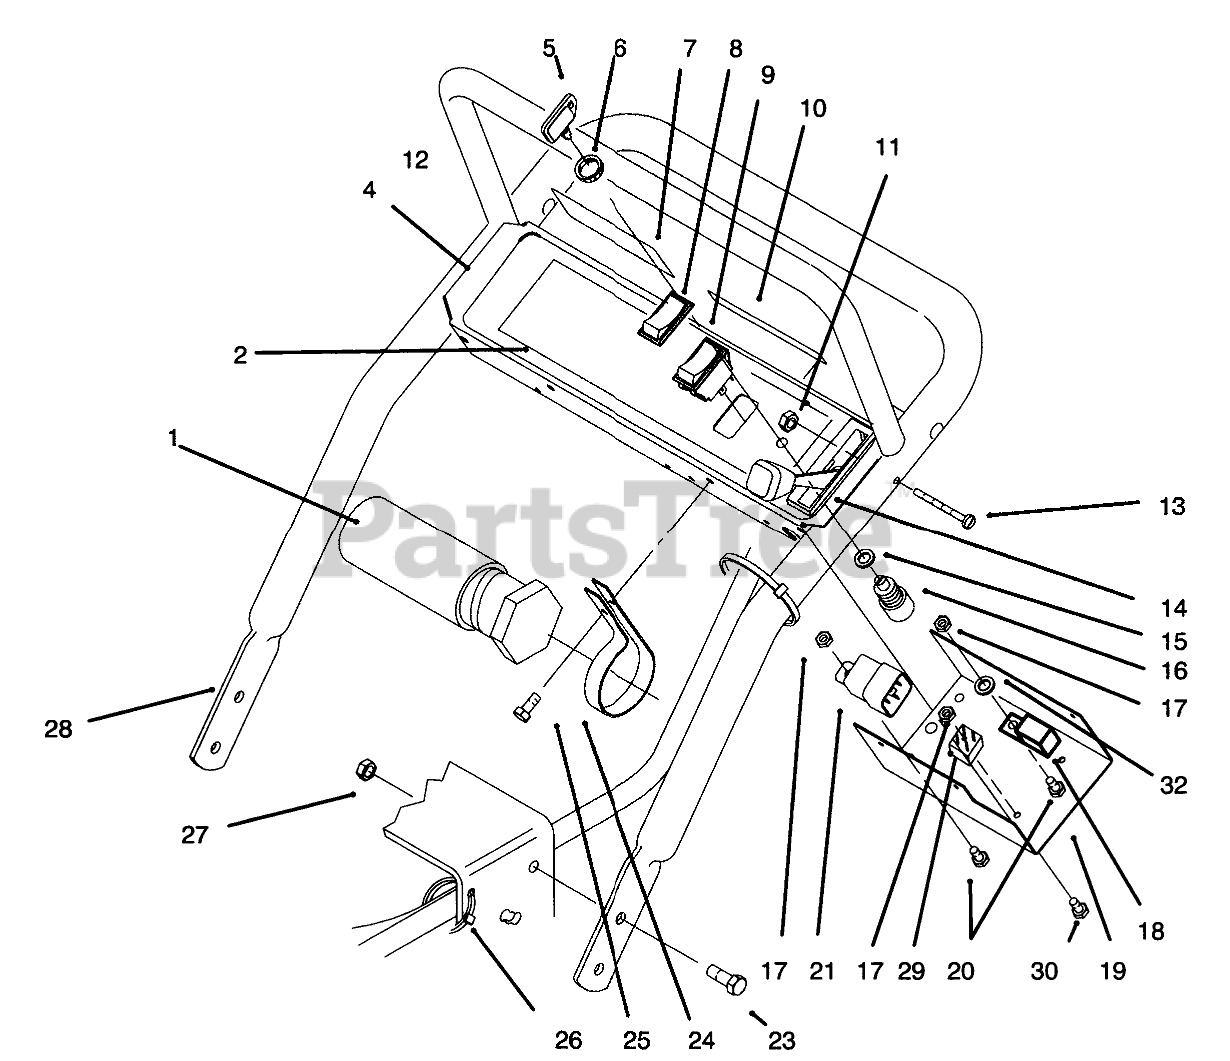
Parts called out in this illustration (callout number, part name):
1	TUBE-MANUAL
2	DECAL - PANEL
4	Panel-Control
5	KEY-IGNITION
6	NUT-HH
7	DECAL-INSTRUCTION
8	BOOT-SWITCH
9	Switch-Clutch (Incl. Ref.#8)
10	DECAL-DANGER
11	NUT-LOCK, NI
13	SCREW-SHH
14	CONTROL-THROTTLE
15	WASHER-TOOTH, INTERNAL
16	Switch-Ignition (Incl. Ref. #5,6, &15)
17	NUT-LOCK, NI
18	Module
19	Panel-Bottom
20	SCREW-HH
21	RELAY
23	SCREW-HHF
24	CLAMP-R
25	SCREW-SHWH
26	TIE-CABLE
27	NUT-HF
28	Handle-Upper
29	RECTIFIER-BRIDGE
30	SCREW-HWH
31	NUT-LOCK, NI
32	WASHER-LOCK/EXT
